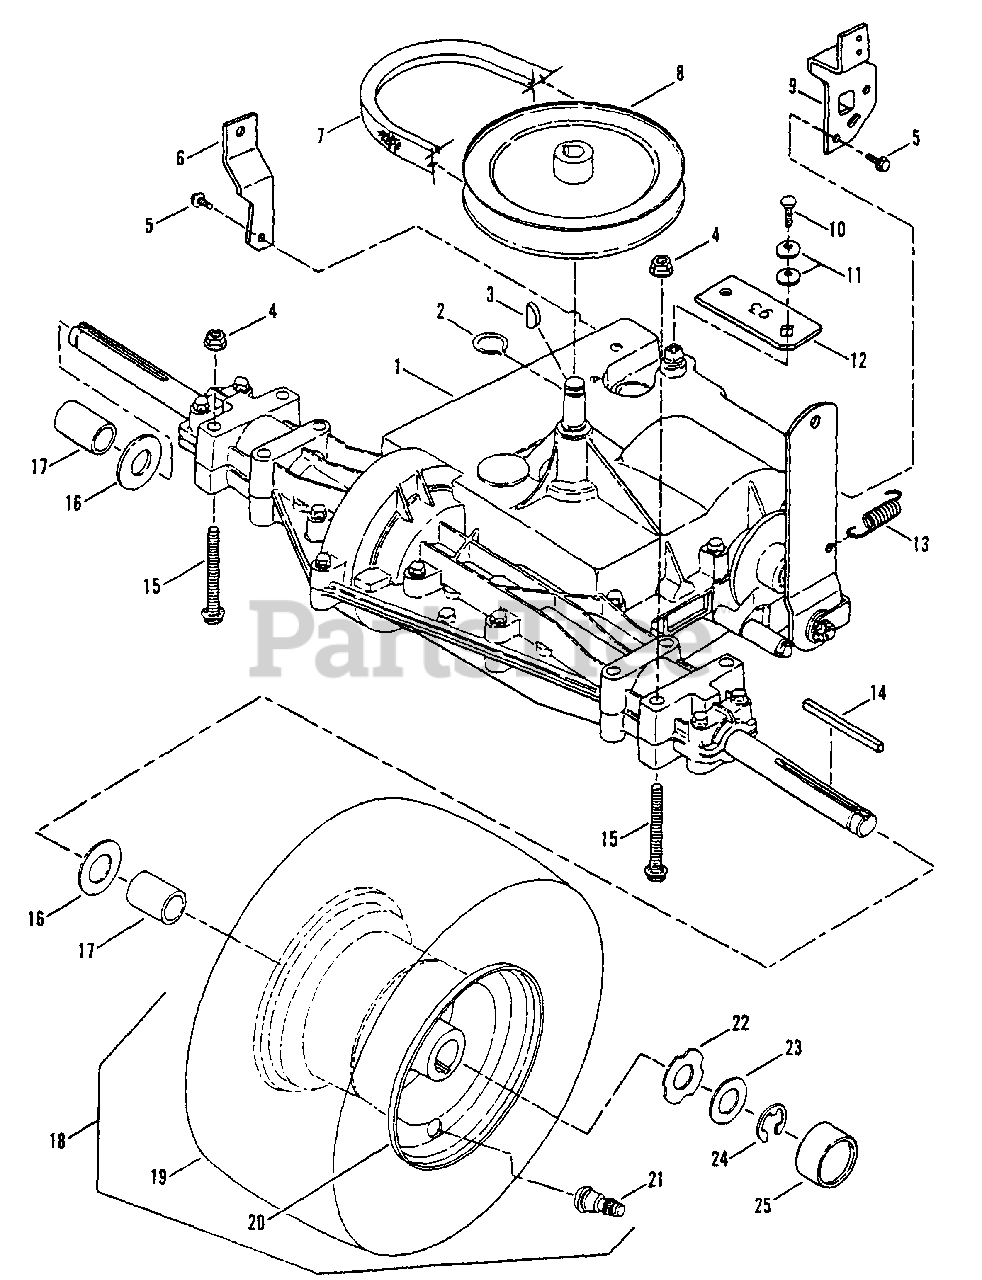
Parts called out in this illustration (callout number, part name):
1	TRANSAXLE, Gear Drive, Peerless Model MST205-514
2	RING, Retaining
3	KEY, Woodruff, 3/16 x 3/4", No. 9
4	NUT, 5/16-18 Hex Flange Lock
5	SCREW, 5/16-18 x 5/8" Hex Washer Head, Self-Tapping
6	BRACKET, Torque
7	BELT, Traction Drive 97.75" EL
8	PULLEY, Drive
9	BRACKET, Axle/Spool
10	BOLT, 1/4-28 x 5/8" Hex Head
11	WASHER, Bellville
12	ARM, Shift Lift Lever
13	SPRING, Brake Return
14	KEY, Square, 3/16 x 3/16 x 2 1/2"
15	BOLT, 5/16-18 x 2 1/4" Hex Flange Lock
16	WASHER, Flat
18	ASSEMBLY, Rear Tire & Rim
19	TIRE, 18 x 8.50
20	RIM, 8 x 7.00
21	VALVE, Snap-In
22	WASHER, Hub-Cap Retaining
23	WASHER, Flat, .07 x .77 I.D. x 1.31 O.D.
24	RING, Retaining
25	HUB-CAP
